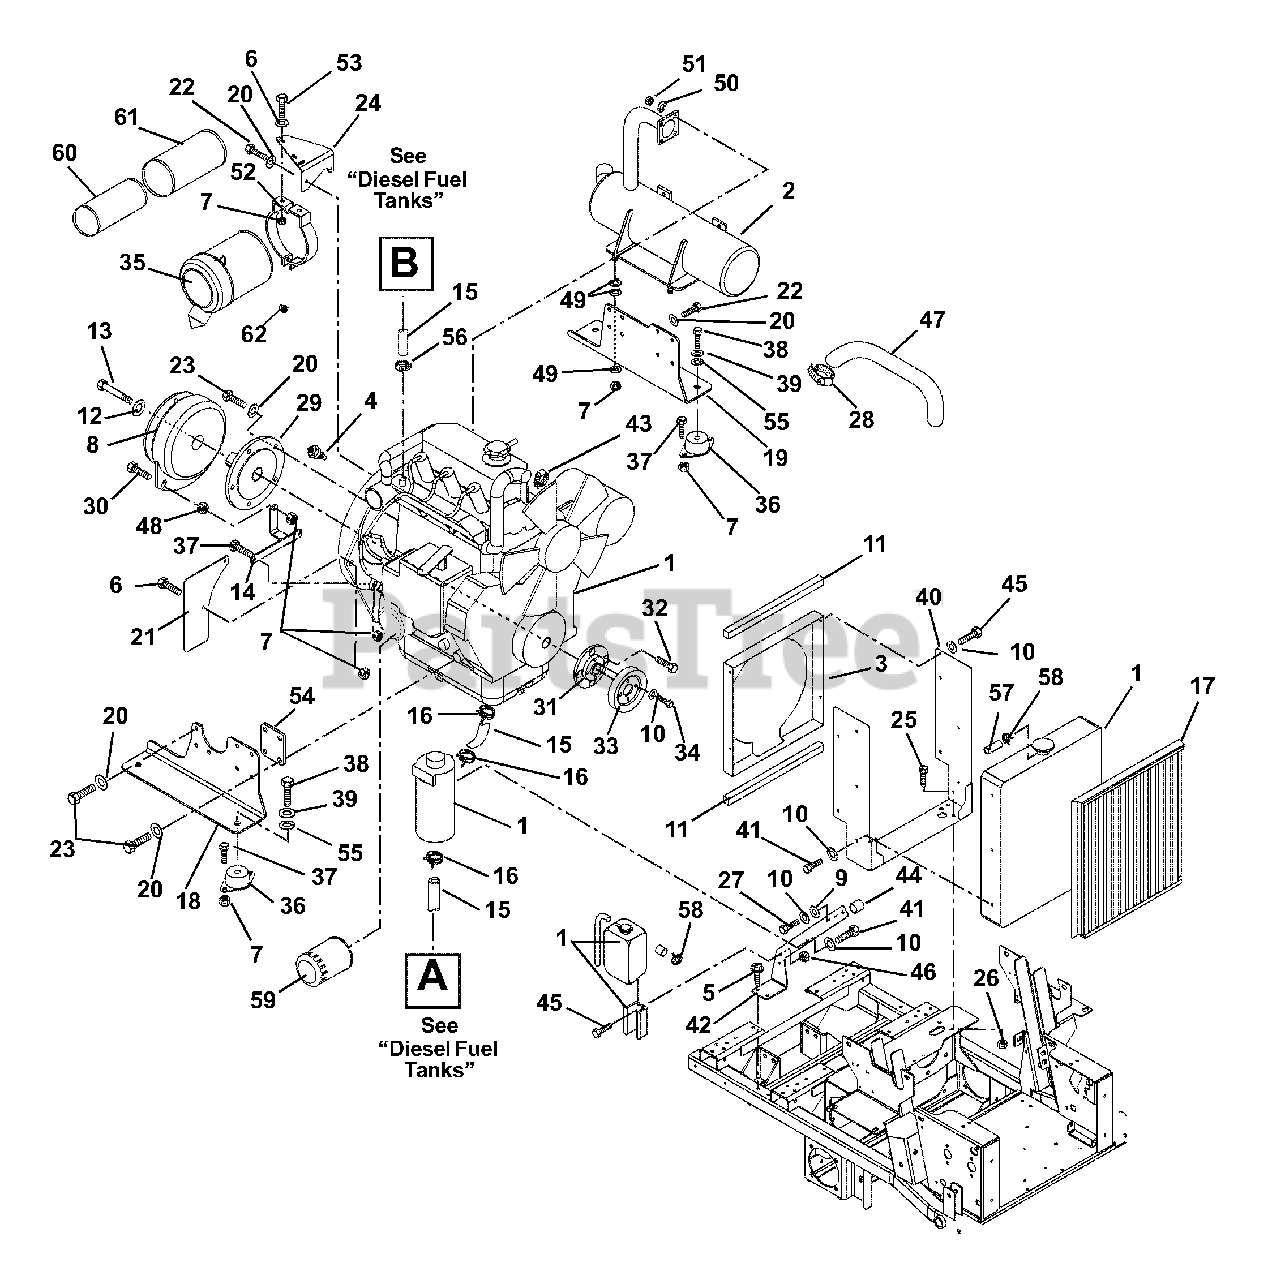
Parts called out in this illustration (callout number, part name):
1	Engine, 27HP Diesel (Daihatsu) (060, 075, 318)
1	Engine, 31HP Diesel (Daihatsu) (061,076, 319)
2	Muffler (060, 075, 318)
2	Muffler (061, 076, 319)
3	Weldment, Radiator Shroud
4	Sender, Temperature
5	Screw, Tapping .38-16 x .75 Hex Washer Head
6	Bolt, Hex .31-18 x .75 Grade 5
7	Nut, Locking Top Flange .31-18
8	Electric Clutch
9	Washer, Flat Steel .281 x .62 x .065
10	Washer, Locking .25 x .062 Regular
11	Seal, Trim-LOK Bulk .06 Bubble
12	Washer, Locking .44 x .109
13	Bolt, Hex .44-20 x 2.50 Grade 5
14	Stabilizer, Clutch
15	Gas Line, Bulk .31" ID
16	Hose, Clamp
17	Screen, Radiator
18	Mount, Engine Right Hand
19	Mount, Engine Left Hand
20	Washer, Lock .31 x .078 Regular
21	Guard, Flywheel
22	Bolt, Hex M8-1.25 x 20
23	Bolt, Hex M8 x 1.25 x 25 Grade 8
24	Bracket, Air Cleaner
25	Bolt, Hex .38-16 x 1.00 Grade 5
26	Nut, Locking Top Flange .38-16
27	Bolt, Hex M6-1.00 x 45
28	Clamp, 2.50" Dia. Hose
29	Weldment, Stub Shaft (061, 076, 319)
30	Bolt, Hex .31-18 x 1.50 Grade 5
31	Adapter, Sheave
32	Bolt,
33	Sheave, Poly-V 1.0 x 3.25
34	Bolt, Hex .25-20 x .75 Grade 5
35	Assembly, Air Cleaner
36	Mount, Engine
37	Bolt, Hex .31-18 x 1.00 Grade 5
38	Bolt, Hex .50-20 x 1.00 Grade 5
39	Washer, Locking .50 x .125 Regular
40	Bracket, Radiator Mounting
41	Bolt, Hex M6-1 x 16
42	Bracket, Overflow Mounting
43	Clamp, Hose 1.50 x .81 x 1.42
44	Spacer .328 x .76 x 1.01
45	Bolt, Hex .25-20 x .75 Grade 5
46	Nut, Locking Top Flange .25-20
47	Hose, Air Cleaner (060, 075, 318)
47	Hose, Air Cleaner (061, 076, 319)
48	Nut, Hex .31-18
49	Washer, Flat Steel .38 x .875 x .083
50	Washer, Locking .31 x .078 Regular
51	Nut, Hex M8-1.25
52	Bracket, Air Cleaner Mount
53	Washer, Flat Steel .38 x .875 x .083
54	Spacer, Engine Mounting
55	Washer, Flat Steel .531 x 1.06 x .095
56	Hose Clamp
57	Gas Line, Bulk .25 I.D.
58	Clamp, Hose Wire .49/.51 x .116
59	Oil Filter
60	Element, Inner Safety
61	Element, Outer Primary
62	Plug, Pipe .125-27
